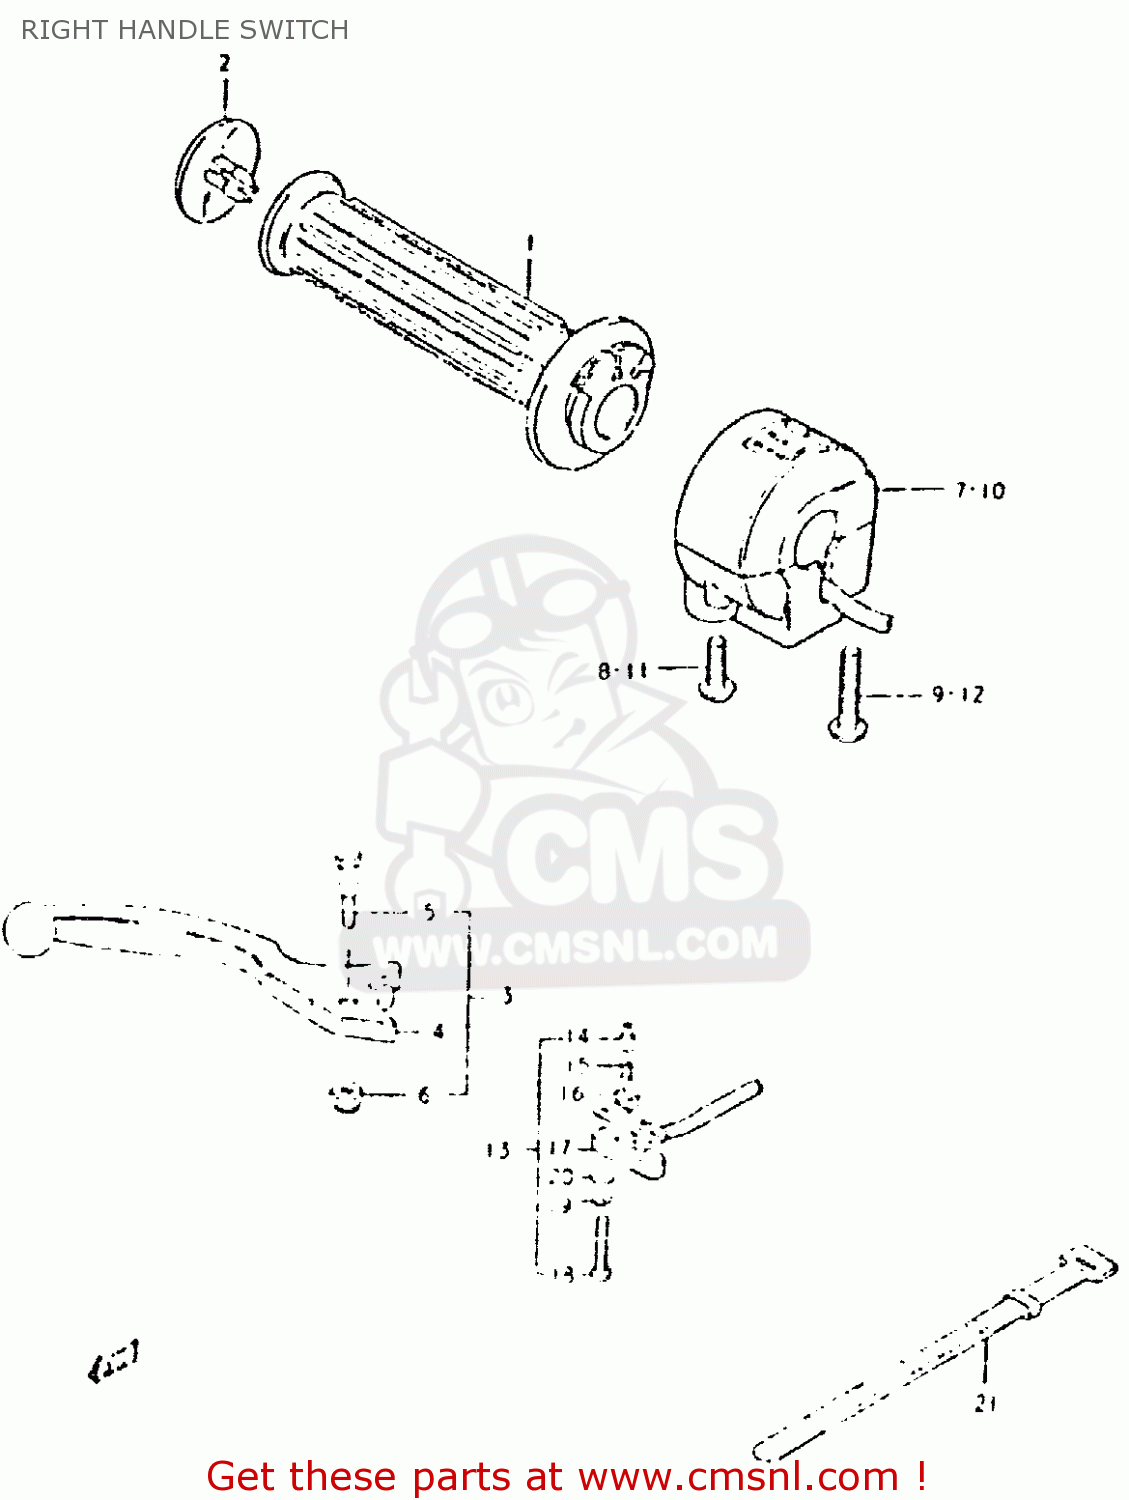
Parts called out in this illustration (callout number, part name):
1	GRIP,THROTTLE
2	CAP,GRIP END
3	LEVER ASSEMBLY,BRAKE
4	LEVER,BRAKE
5	BOLT
6	NUT 6MM
7	SWITCH ASSEMBLY,HANDLE,RIGHT
8	SCREW
9	SCREW
21	CLAMP(L:120)
